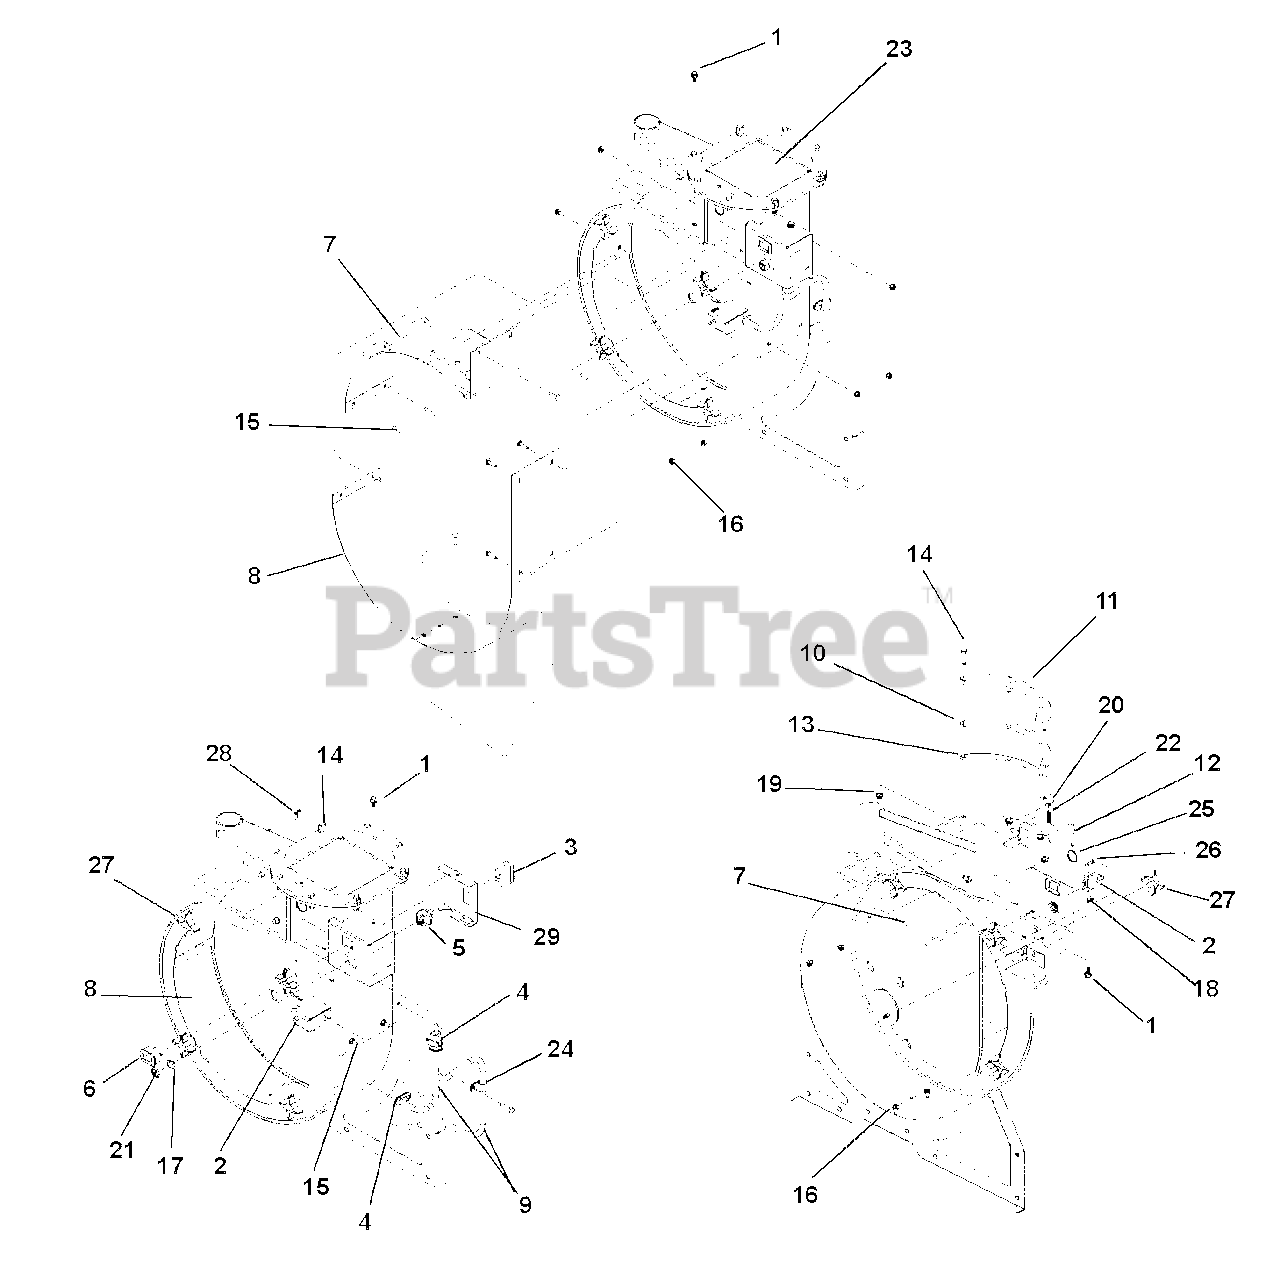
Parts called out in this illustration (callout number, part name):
1	Bolt, 5/16-18 x .625 Grade 5
2	Switch, Plunger N.O.-N.C
3	Switch, Rocker Momentary Rev 0
4	Grommet, Rubber .881 D x .14 GR
5	Key Switch
5	Ignition Key
6	Meter, Hour Smart Sense without SV
7	Baffle, 22 HP (995042)
7	Baffle, 18 HP (995041)
8	Plate, Liner 22 HP (995042)
8	Plate, Liner 18 HP (995041)
9	Wire Harness, Truck Loaders
10	Spacer, Flange
11	Flange, Top
12	Pin, Spring Latch
13	Spacer, Flange .060
14	Bolt, Hex .31-18 x 1.25 Grade 5 YWZC
15	Bolt, Round Head Square Neck .25-20 x 1.00 Grade 5 YWZC
16	Nut, .25-20 Nyloc Flange
17	Nut, Panel .562-24 Grieco
18	Nut, Nyloc 10-24 w/insert YWZX
19	Nut, Nyloc .31-18 Flange YXZC
20	Washer, Flat .281 x .62 x .065 Stl YWZC
21	Cap, Ignition Switch
22	Spring, Compression .028 x .34 x 1.062
23	Weldment, Fan Housing Assembly w/Decals 22 HP (995042)
23	Weldment, Fan Housing Assembly w/Decals 20 HP (995041)
24	P-Clip, Insulated .750
25	Ring, Retaining
26	Strip, Backup
27	Knob, 5/16 Thread
28	Screw, Machine 8-32 x .62 Nickel
29	Weldment, Switch Cover
